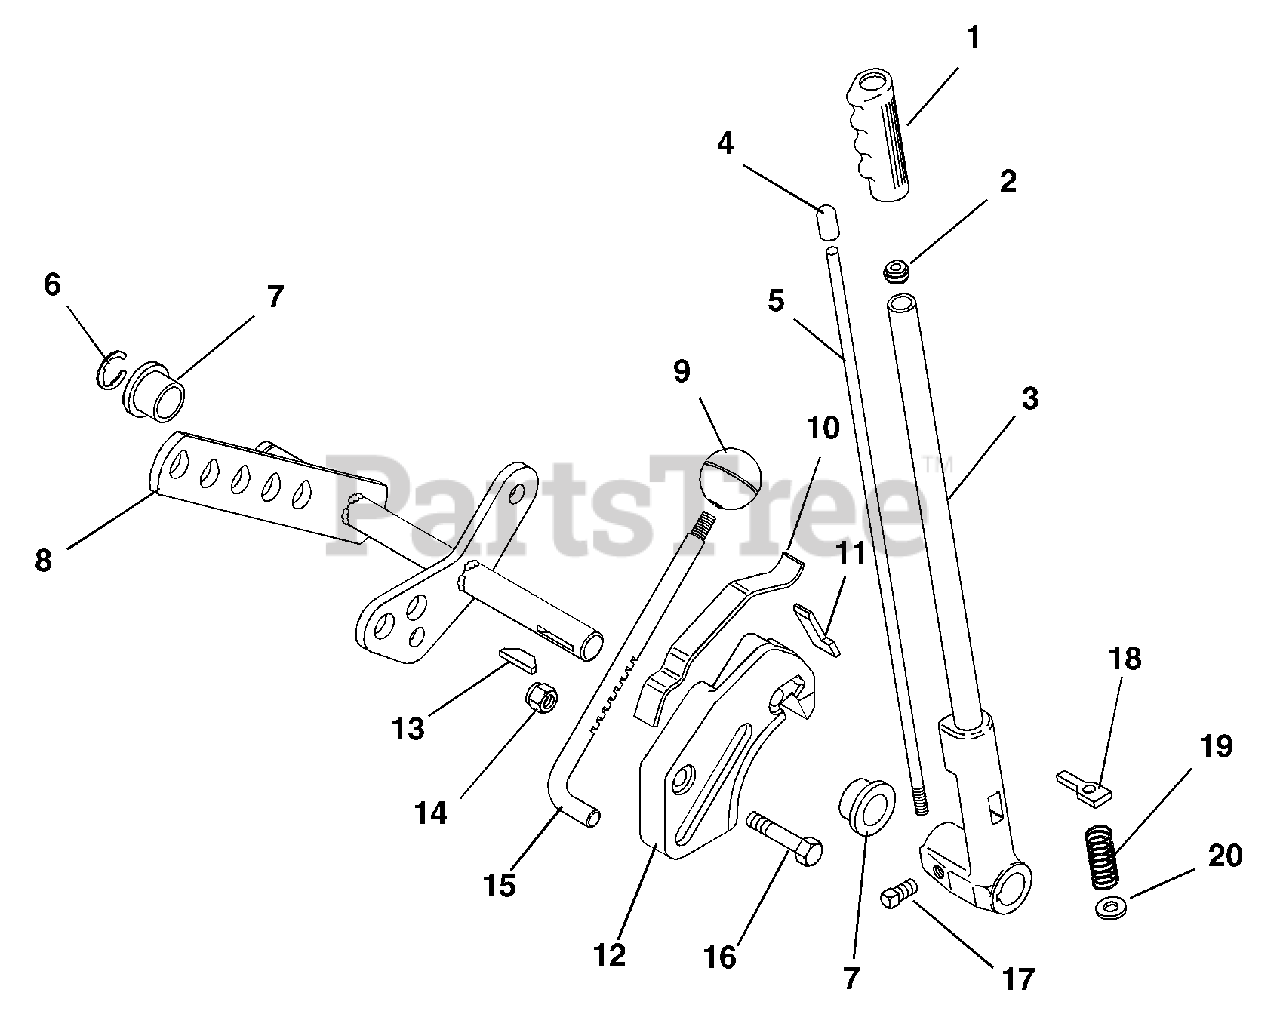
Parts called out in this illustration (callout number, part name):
1	Handle Grip
2	Guide, Push Rod
3	Assembly, Lever Lift
4	Tip, Push Rod
5	Rod, Lever Push
6	Ring-Retaining-External .84 x .056
7	Bushing-Flange 1.02 x 1.39 x .75 x 1.75 Nylon
8	Shaft, Lift Lever Weldment
9	Knob-Control .44-20 x .50
10	Spring, Stop
11	Stop, Lever
12	Casting, Locator
13	Key-Woodruff .25 x 1.38 x .41 SAE 127
14	Nut-Locking-Center .38-16
15	Rod, Lever Stop
16	Bolt-Hex .38-16 x 1.25 Grade 5
17	Screw-Set .38-16 x .50
18	Pawl, Lever
19	Spring-Compression .07 x .72 x 2.00
20	Washer-Flat-Steel .44 x 1.00 x .083
